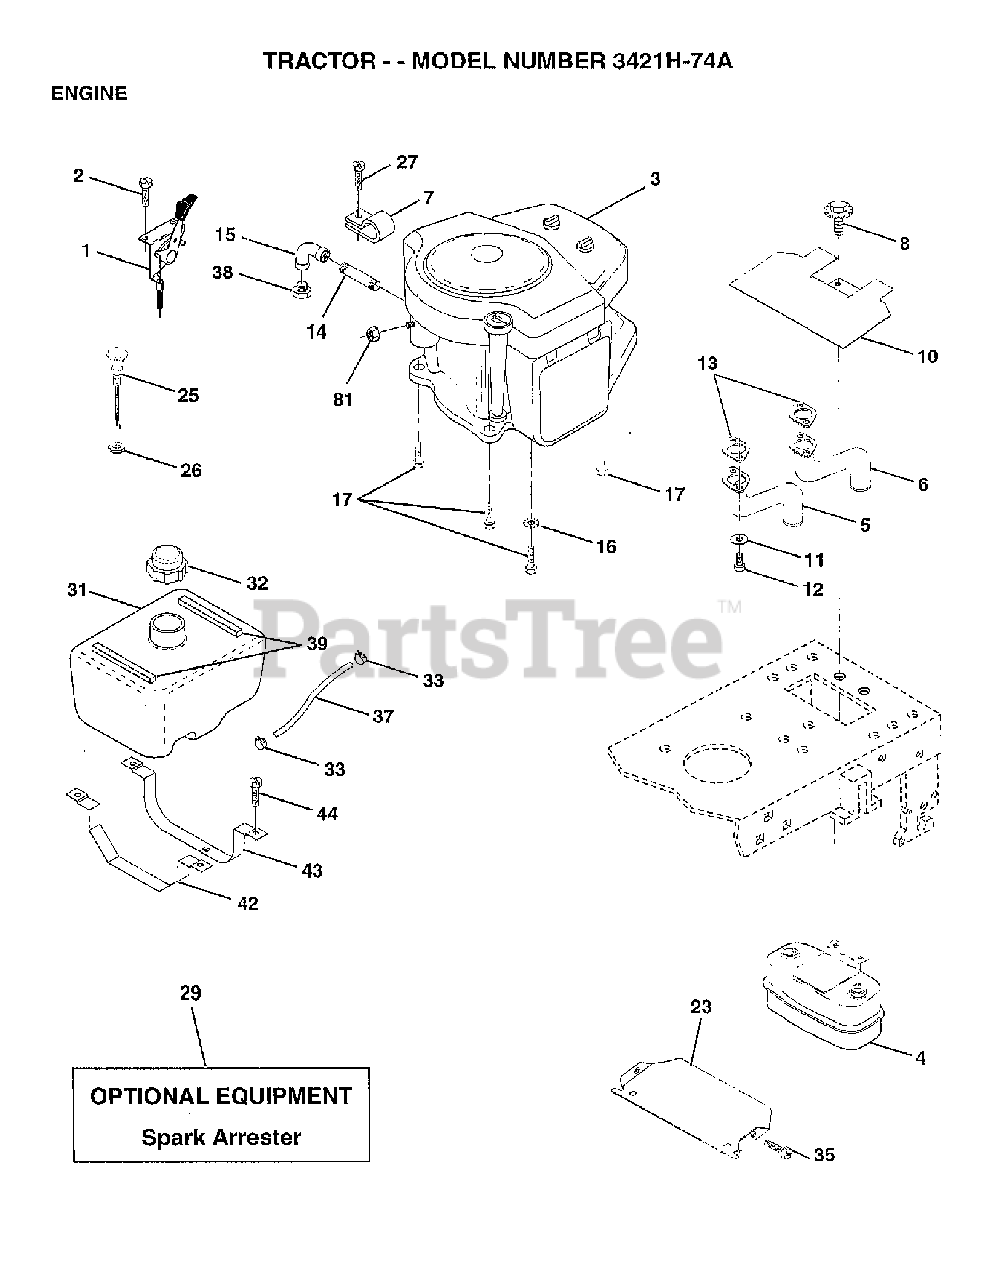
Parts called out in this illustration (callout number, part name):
1	DECK W/DECALS 72" HUS
3	Poulan TBD
4	MUFFLER.TWIN.CYL.LOW.TONE
5	EXHAUST ASM. LEFT
6	EXHAUST ASM. RIGHT
10	SHIELD HEAT LT
14	NIPPLE, PIPE 3/8NPT X 4-1/2
15	ELBOW
16	LOCKWASHER
25	CONTROL.CHOKE.51.00.BLK.W/BEND
26	NUT KEPS 3/8 - 24 UNF
27	SCREW.TT.#10-32X.5.3/8.FLANGE
29	KIT.SPARK ARRESTOR(392390 B&S)
33	HOSE CLAMP
35	Screw, Lt
37	LINE FUEL 7.5"
